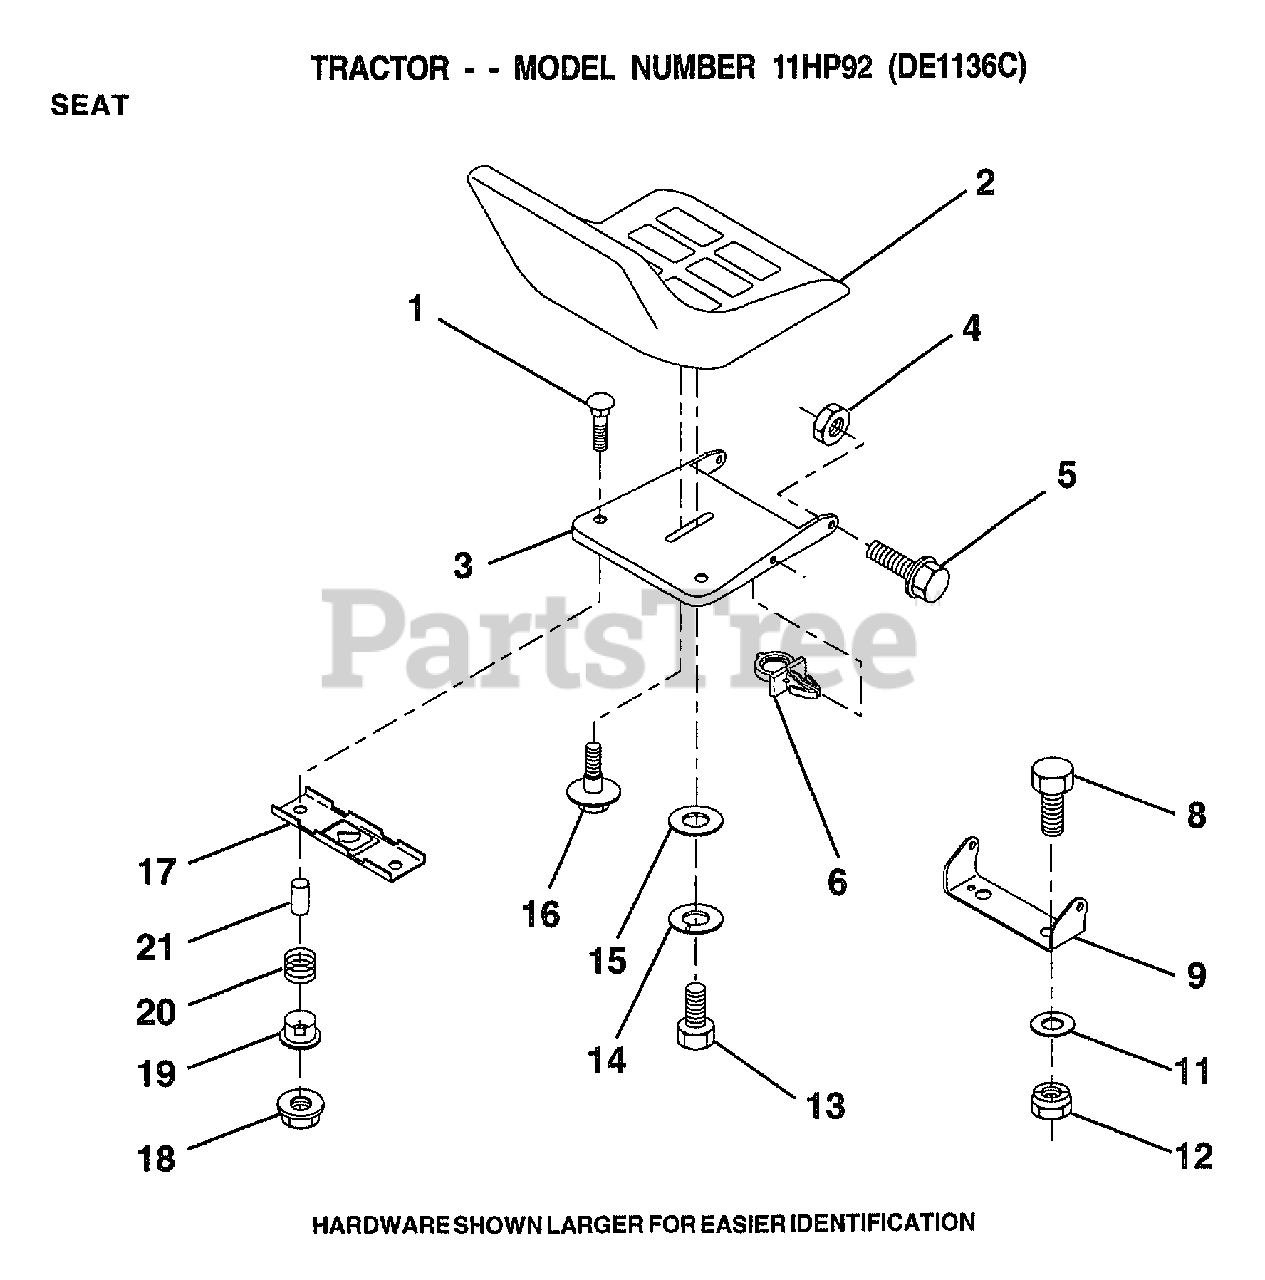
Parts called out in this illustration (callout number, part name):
1	BOLT-RD HD SQ NK
3	PAN-SEAT
4	NUT
5	BOLT
6	CLIP.PUSH-IN.HING
8	BOLT
9	BRACKET PVT SEAT
11	WASHER
12	NUT
13	BOLT
14	LOCKWASHER
15	WASHER
16	"BOLT,SHOULDER"
17	BRKT SWITCH
19	BUSHING
20	SPRING
21	SPLIT SPACER
